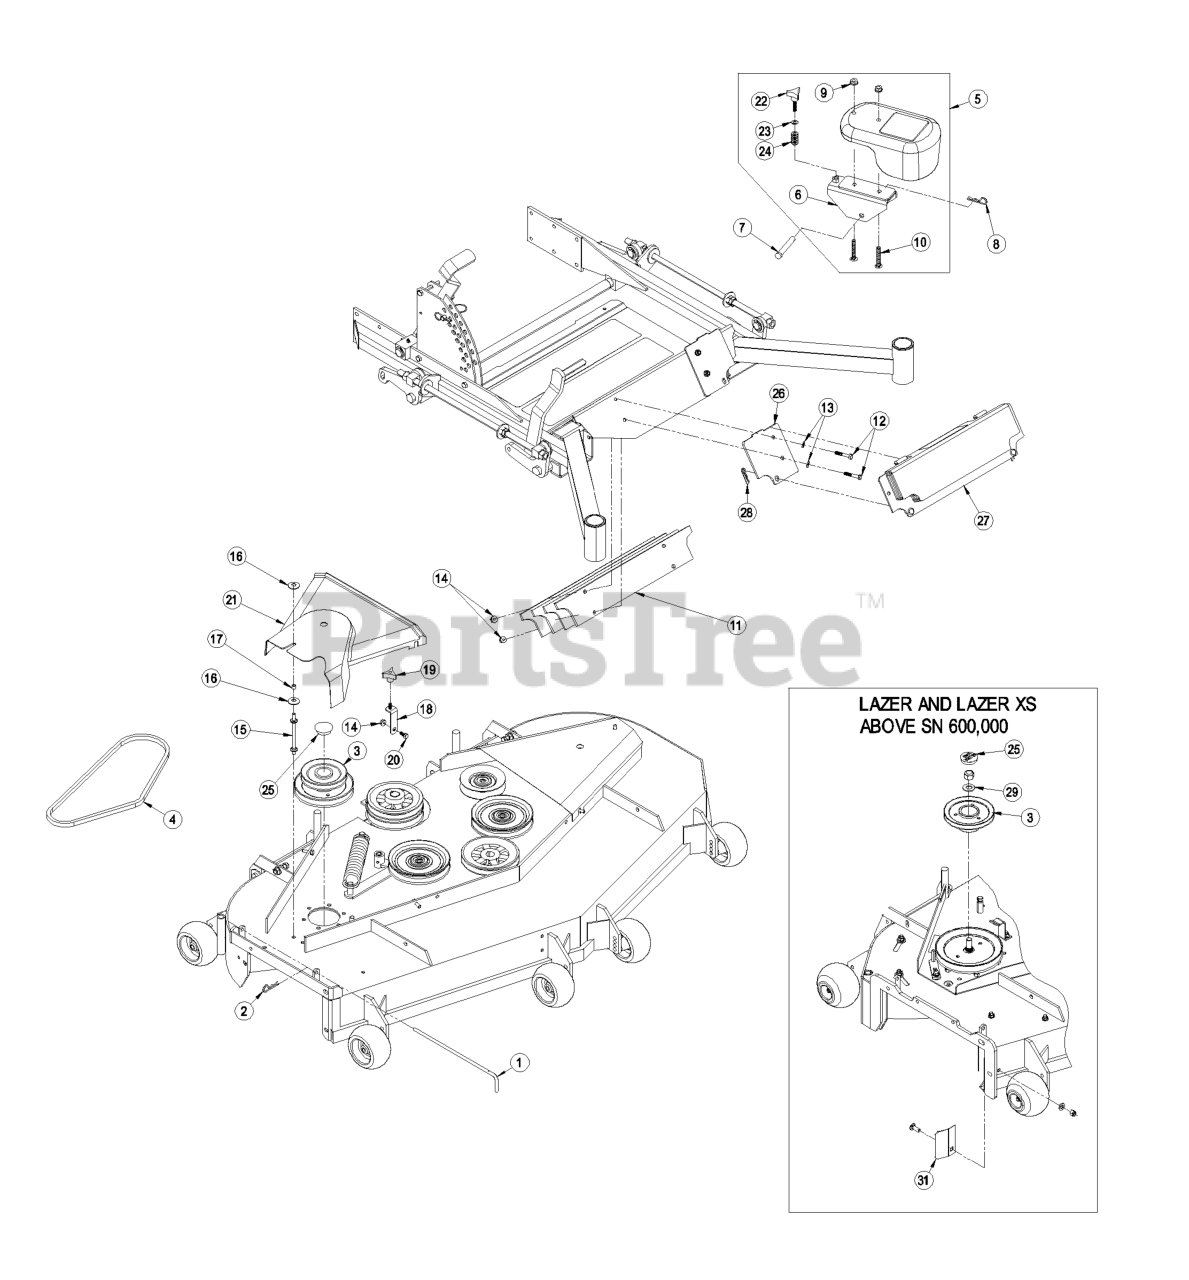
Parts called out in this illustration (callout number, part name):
1	PIN,CHUTE PIVOT
2	PIN-COTTER
3	JACKSHAFT, LZUV72
4	BELT, BLOWER DRIVE 72
5	ASM, WEIGHT 2.0" 43 POUND
6	WLD, BRACKET 2.0 ARM
7	PIN-CLEVIS
8	PIN-COTTER
9	NUT-HHF, WHIZ
10	BOLT-SQH
11	PLATE, WEIGHT
12	SCREW-HH
13	WASHER-PLAIN
15	STUD,BELT SHIELD 4 INCH
17	Spacer, Grommet
18	Support, Belt Cover
19	Knob
21	COVER, BELT 72
23	WASHER-FLAT
25	PLUG, BLACK NYLON 1.75
26	PLATE, WEIGHT MOUNTING
27	ASM, WEIGHT PLATE WITH DE
28	PIN-HAIR
29	WASHER-FLAT
31	Deflector
